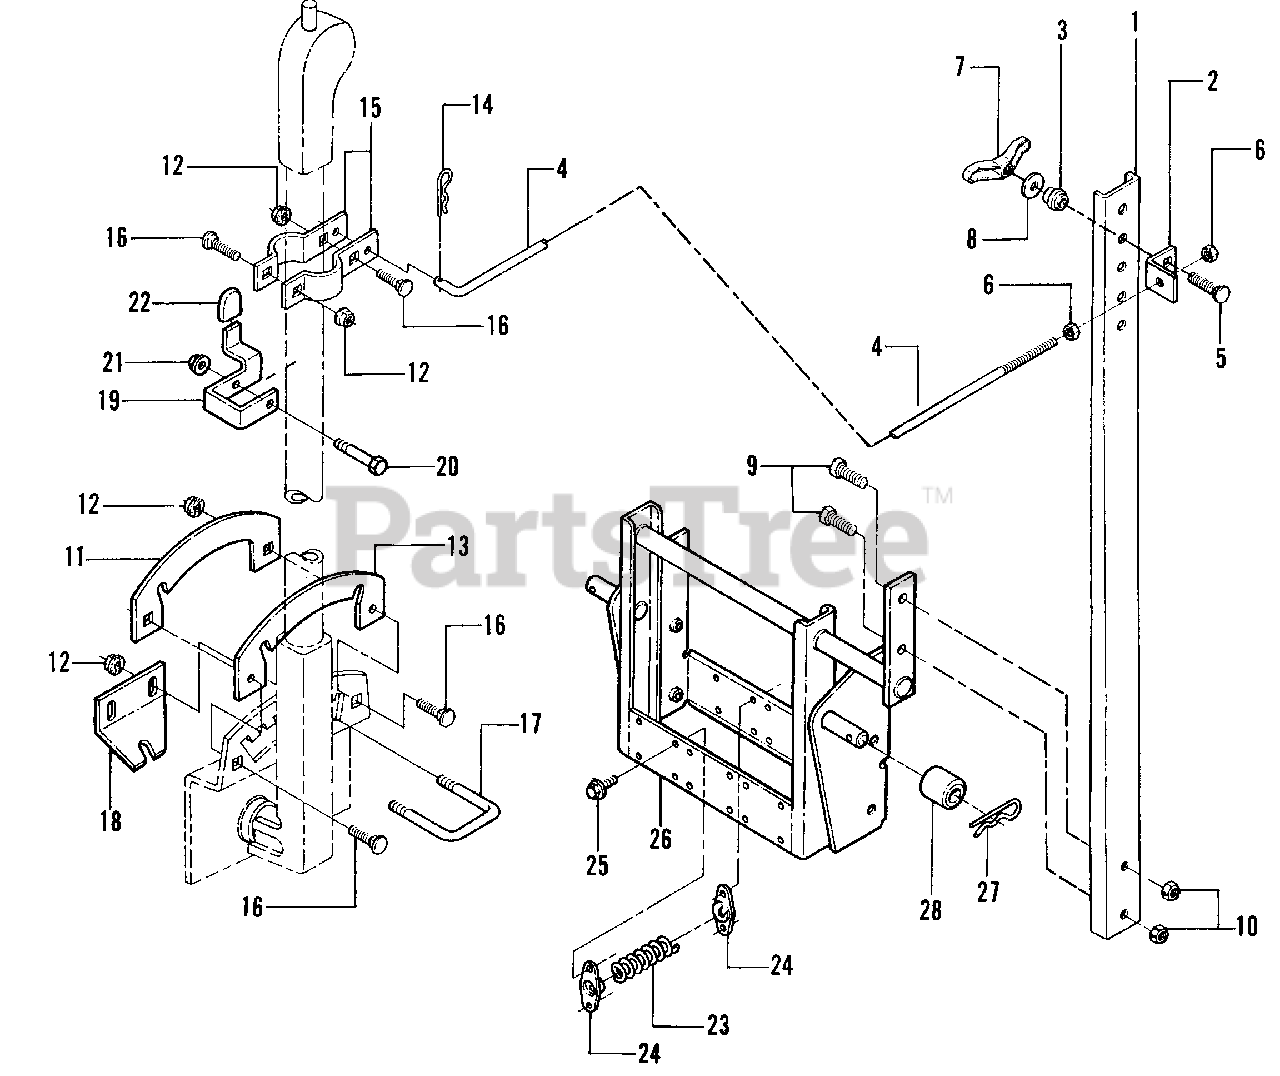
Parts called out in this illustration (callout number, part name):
1	ARM, Lift
2	SWIVEL, Lift Rod
3	SPACER
4	ROD, Lift
5	BOLT, 5/16-18 x 2 1/2" Short Neck Carriage
6	NUT, 3/8-16 Hex
7	NUT, 5/16-18 Wing
8	WASHER
9	SCREW, 1/2-13 x 1" Hex Flange Lock
10	NUT, 1/2-13 Hex Flge. Lk.
11	PLATE, Quadrant Float
12	NUT, 1/4-20 Hex Flge. Lk.
13	PLATE, Quadrant
14	PIN, 3/32 x 1 1/2" Hair
15	TAB
16	BOLT, 1/4-20 x 1/2" Short Neck Carriage
17	BOLT, 1/4-20 Square "U"
18	PLATE, Mounting
19	BRACKET
20	SCREW, 1/4-20 x 1 3/4" Hex Head Cap, Grade 5
21	NUT, 1/4-20 Hex Center Lock
22	COVER, Bracket
24	RETAINER, Spring
25	SCREW, 1/4-20 x 1/2" Hex Head Cap, Self-Tapping
26	STRUCTURE, Lift Bracket
27	PIN, Hair
28	BUSHING, Hitch
